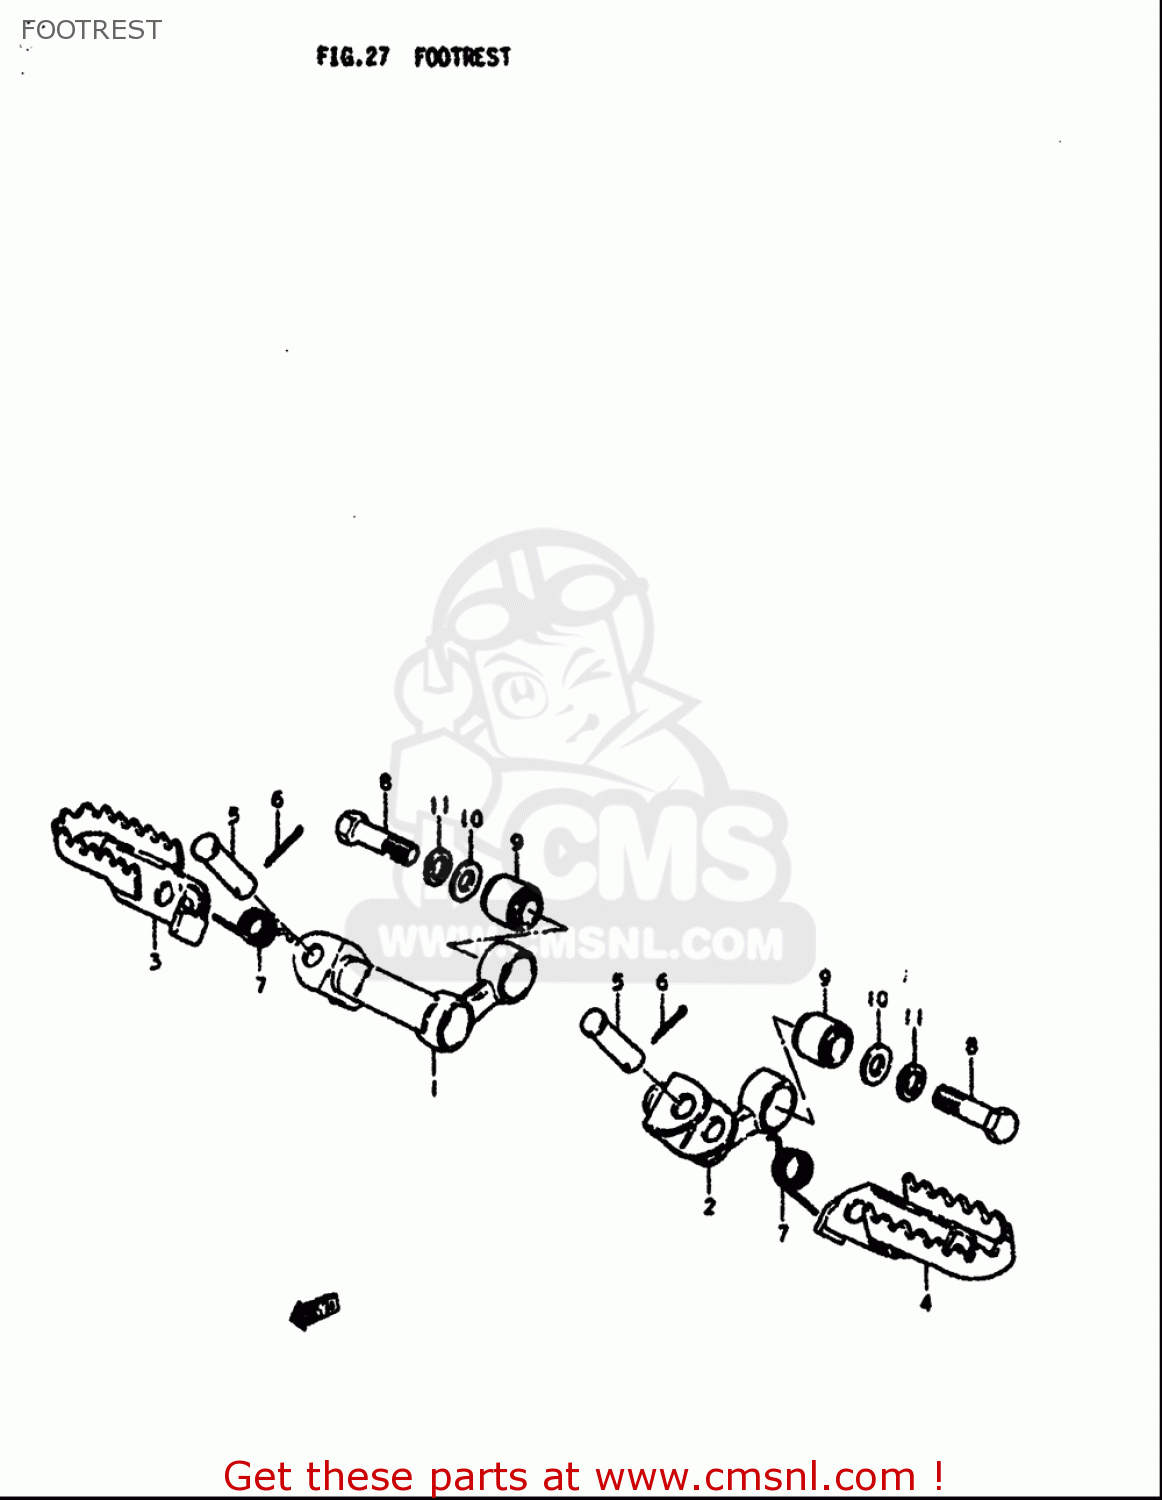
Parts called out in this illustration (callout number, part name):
3	FOOTREST,FR,R
4	FOOTREST,FR,L
5	PIN
6	PIN
7	SPRING
8	BOLT(10X38)
9	BUSH
10	WASHER(10.5X20X2.3)
11	WASHER,LOCK
